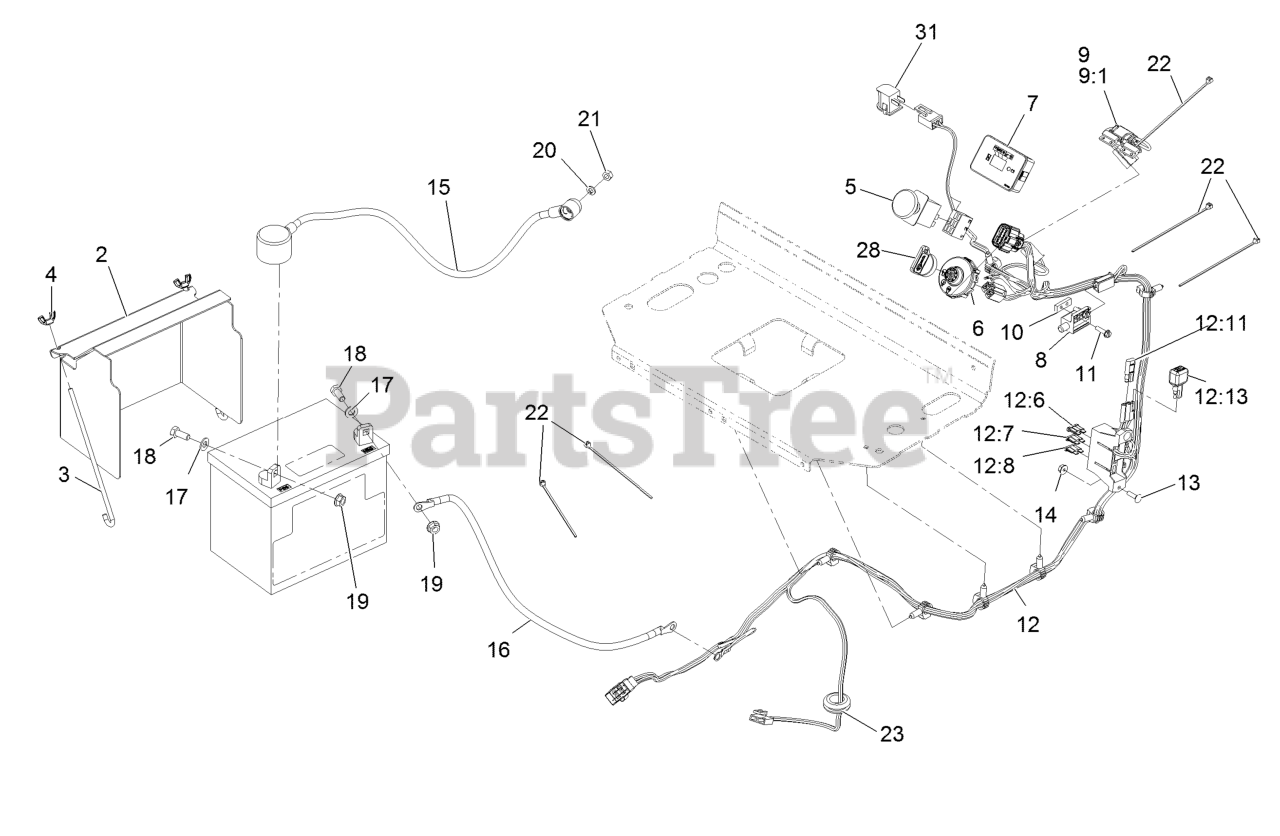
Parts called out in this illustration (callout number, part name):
2	Cover-Battery
3	Bolt-Holddown
4	Wingnut-Nyloc 1/4-20
5	Switch-PTO, On-On-(On)
6	Switch-Ignition
7	Module-Hour Meter
8	Switch-N.C.
9	Harness-Switch, Reed
9:1	Harness-Wire, Reed Switch
10	Plate-Tapped
11	Screw-HWH #10-24 X 3/4
12	Harness, Wire
12:6	Fuse-Blade, 30 Amp
12:7	Fuse-Blade, 25 Amp
12:8	Fuse-Blade, 10 Amp
12:11	Cap-Plug
13	Screw-CARR
14	Nut-Whizlock #10-24
15	Cable-Battery, Positive
16	Cable-Battery, Black
17	Washer-5/16 SAE
18	Screw-HH 5/16-18 X 3/4
19	Nut-Hex Flange 5/16-18
20	Washer-Lock 1/4
21	Nut-Hex 1/4-20
22	Tie-Cable 5 1/2 (Small)
23	Grommet
28	Key-Exmark Logo
